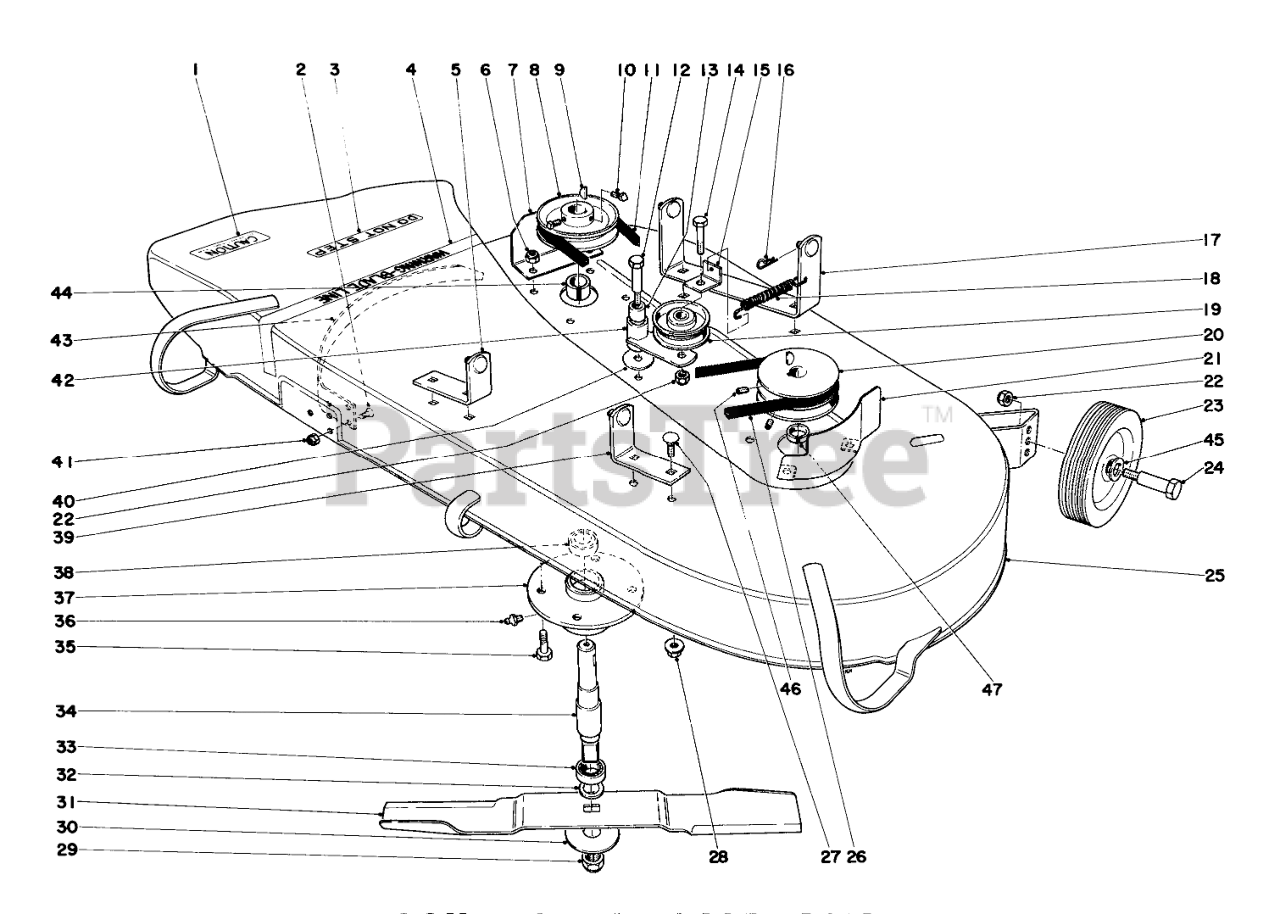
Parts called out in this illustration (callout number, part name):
1	Decal
2	Capscrew, Flat Hd.
3	Decal
4	Decal-Blade Line
5	Mounting Bracket
6	NUT-LOCK, CONE
7	Guard-Pulley
8	Pulley
9	KEY-WOODRUFF
10	5/16-18 X 1/2 SQ HD
11	V-Belt
12	Axle Bolt
13	BUSHING
14	SCREW-HH
16	PIN-COTTER
17	Mounting Bracket
18	Spring-Tension
19	PULLEY-IDLER
20	BLD SPDLE PULLEY (MACH)
21	Pulley Guard
22	NUT-LOCK, CONE
23	Wheel
25	Housi ng
26	V-Belt
27	SCREW-CARR
28	NUT-HF
30	WASHER
31	Blade
32	WASHER
33	.6693 RP BALL BEARING
34	Spindle Blade
35	SCREW-HH
36	FITTING-GREASE
37	Housing Mower Spindle
38	Bearing
39	Mounting Bracket
40	WASHER
41	NUT-LOCK, NI
42	Idler Plate (Incl. Ref. #13)
43	Deflector Bar
44	Spacer
45	WASHER-FLAT
46	SCREW-SET, HSH
47	Spacer Split
